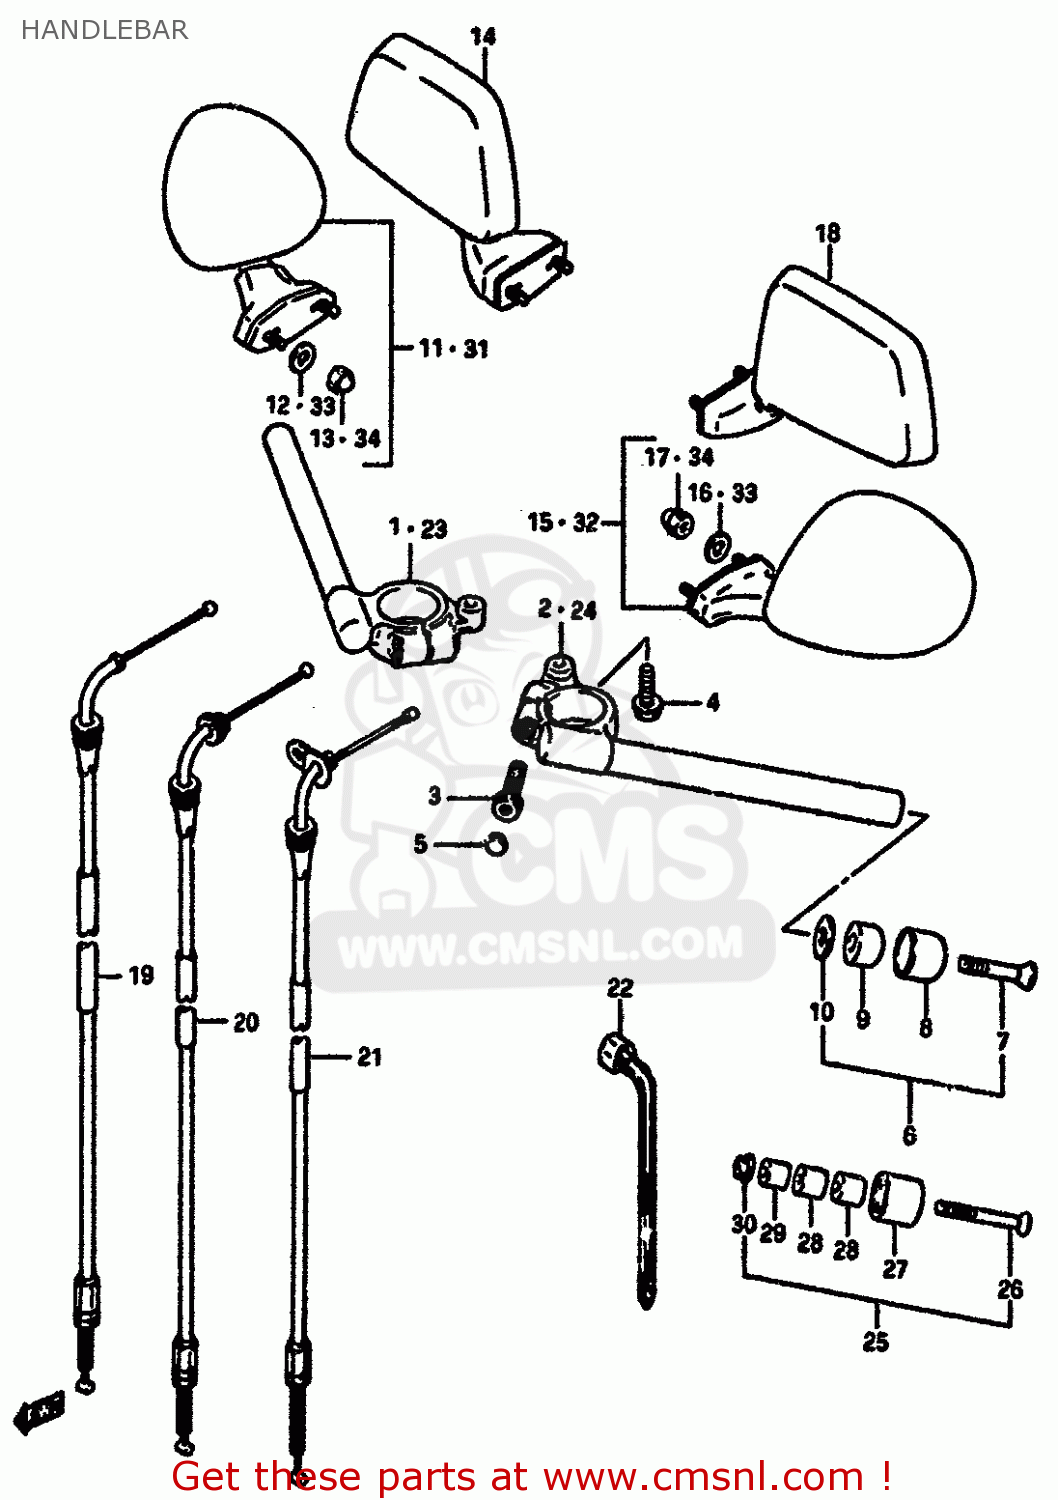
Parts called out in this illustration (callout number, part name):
1	HANDLEBAR,RIGHT
2	HANDLEBAR,LEFT
3	BOLT 8X35
4	BOLT
5	CAP(OD:10)
6	BALANCER SET,HANDLEBAR
7	SCREW
8	CAP,BALANCER
9	BALANCER,HANDLE
10	SPACER,BALANCER
11	MIRROR ASSY,REAR VIEW RH
12	WASHER
13	NUT 6MM
14	MIRROR ASSY,RH
15	MIRROR ASSY,REAR VIEW LH
16	WASHER
17	NUT 6MM
18	MIRROR ASSY,LH
19	CABLE ASSY,THROTTLE NO.1
20	CABLE ASSY,THROTTLE NO.2
21	CABLE ASSY,THROTTLE
22	CLAMP(L:165)
23	HANDLEBAR,RIGHT
24	HANDLEBAR,LEFT
25	BALANCER SET,HANDLEBAR
26	SCREW(6X85)
27	CAP,BALANCER
28	BALANCER,HANDLEBAR INNER
29	EXPANDER,HANDLE BALANCER
30	NUT
31	MIRROR ASSY,REAR VIEW RH
32	MIRROR ASSY,REAR VIEW LH
33	WASHER
34	NUT 6MM
